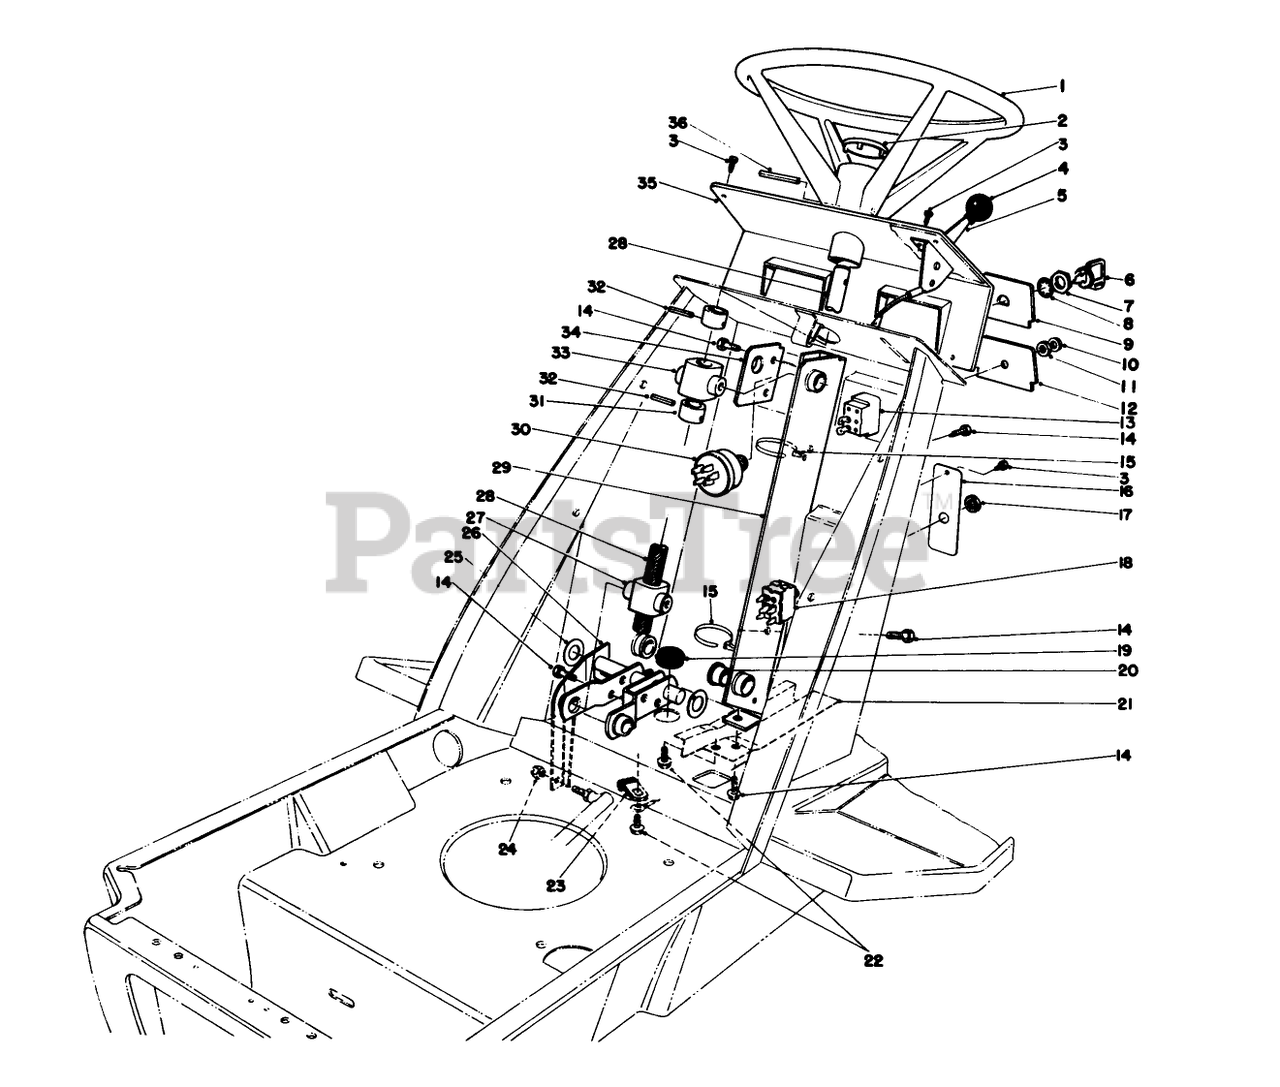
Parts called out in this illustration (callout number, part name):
1	STEERING WHEEL ASM
3	SCREW-HWHTF
4	KNOB-CONTROL
5	THROTTLE CONTROL
6	KEY-IGNITION
7	NUT-HH
8	WASHER-LOCK
11	NUT-LOCK
13	Light Switch
14	SCREW-THD ROLL, HWH
15	TIE-CABLE
19	GROMMET
20	BEARING-FLANGE
22	SCREW
23	CLIP-FUEL LINE
24	NUT-HEX
28	STEERING SHAFT
30	SWITCH-STARTER
31	STRG SHAFT COLLAR
32	PIN-SPRING
36	PIN-ROLL
